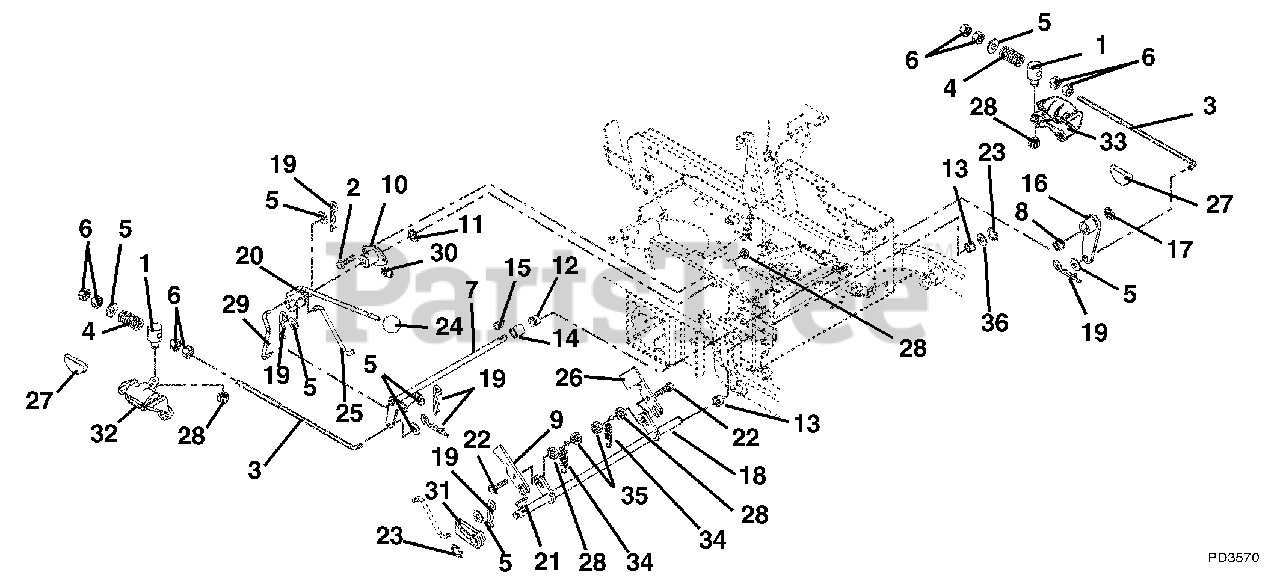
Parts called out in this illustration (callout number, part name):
1	Pivot-Brake Rod
2	Bolt-Hex .31-18 x .75 Grade 5
3	PTO Link Rod
4	Spring-Compression .143 x .710 x 2.00
5	Washer-Flat-Steel .406 x .812 x .065
6	Nut-Hex .38-16
7	Weldment, Brake Cross Shaft
8	Bushing-Flange Nylon .63 x 1.00 x .625
9	Slide, Interlocking Brake
10	Bushing, Flange
11	Ring-Retaining-External .625 x .05
12	Bushing-Flange Nylon .762 x 1.00 x .58 x 1.48
13	Bushing-Flange .50 x .75 x .75 x 1.00
14	Bushing-Sleeve .75 X 1.00 X .75
15	Key-Woodruff .19 x .75 Hard #9
16	Arm-Brake Left-Hand
17	Ring-Retaining-External .625 x .050
18	Weldment, Mechanical Brake
19	Pin, Hair
20	Weldment, Brake Actuating
21	Key-Woodruff .13 x .63
22	Bolt-Hex .31-18 x 1.25 Grade 5
23	Ring-Retaining-External .50 x .05
24	Knob, Steering Lock
25	Linkage, Brake Actuating
26	Interlock, Safety Switch
27	Pad, Disk Brake
28	Nut-Locking-Top-Flange .31-18
29	Linkage, Brake Actuating
30	Fitting-Lube .25-28 x .256
31	Weldment, Parking Brake Hub
32	Brake, Right Hand Caliper
33	Brake, Left Hand Caliper
34	Spring-Tension .061 x .50 x 3.0
35	Nut-Locking-Center .31-18
36	Washer-Flat-Steel .505 x 1.00 x .062
